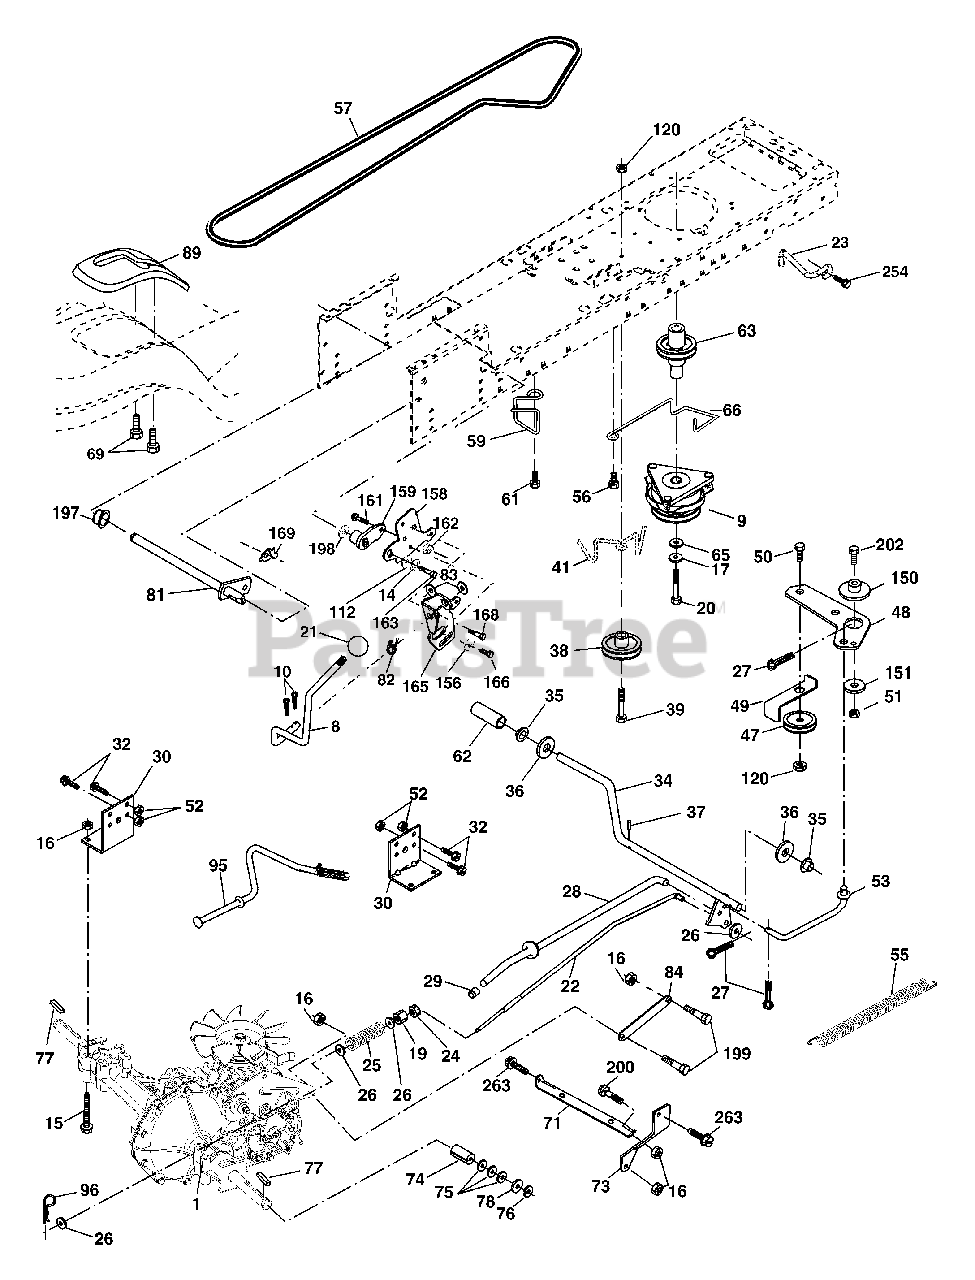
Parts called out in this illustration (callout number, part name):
8	Rod Shift Fender Adjust STLT
9	Clutch Elecric
10	Pin Cotter 1/8 x 1 CAD
14	Washer Lock Hvy Helical
15	Bolt Hex 5/16-18 unc Flghd
16	Nut Lock Hex W/Ins. 5/16-18 unc P
19	Nut Lock Hex W/Ins 3/8-16 unc
20	Bolt, Hex 7/16-20 x 4-1/4 Ga. 5
21	Knob Deluxe 1/2-13 unc BLK/BLK
22	Rod, Brake Hydro
23	Bracket Asm Mtg CL
24	Nut Hex Jam 3/8-16 unc
25	Spring, Brake Rod
26	Washer
27	Pin Cotter 1/8 x 3/4 CAD.
28	Rod, Parking Brake
29	Cap,Parking Brake
30	Bracket, Transaxle
32	Bolt Hex Hd 5/16-18 unc x 3/4
34	Shaft, Foot Pedal
35	Bearing, Nylon
37	Pin, Roll
38	Pulley, Composite
39	Bolt Rdhd 3/8-16 unc x 2-3/4 Gr. 5
41	Keeper, Belt Idler
47	Pulley, Idler, V-Groove Plastic
48	Bellcrank Clutch Grnd Drv STL
49	Retainer, Belt Style Spring
50	Bolt 3/8-16 x 1-1/2 Gr. 5
52	Nut Crownlock 5/16-18
53	Link, Clutch
55	Spring, Return, Clutch
56	Screw 3/8-16 x 1-1/4
57	V-Belt, Ground Drive
59	Keeper, Center Span
61	Screw 3/8-16 x .875
62	Cover, Pedal
63	Pulley, Engine
65	Washer Lock Hvy HLCL Spr 7/16
66	Keeper Belt Engine
69	Screw Hex Wsh Hi-Lo 1/4-1/2 unc
71	Strap Torque Lh Hydro
73	Strap Torque Rh Hydro
74	Spacer, Axle
75	Washer 25/32 x 1-1/4 x 16 Ga.
77	Key, Square
78	Washer 25/32 x 1-5/8 x 16 Ga.
81	Shaft Asm Cross Tapered
82	Spring Torsion T/A
83	Washer 17/32 x 3/4 x 16 Ga.
84	Link Transaxle
89	Console, Shift
95	Control Asm. Bypass Hydro
96	Retainer Spring 1" Zinc/Cad
112	Washer 9/32 x 3/4 x 10 Ga.
116	Bolt Rdhd Sqnk 3/8-16 unc x 1
120	Nut Lock Flg 3/8-16
150	Spacer Retainer
151	Washer 13/32 x 2 x 10 Ga.
156	Washer Srrted 5/16 ID x 1.125
158	Bracket Shift Mount
159	Hub Shift
161	Bolt Rdhd Sqnk 1/4-20 x 3/4 Gr. 5
162	Nut Crownlock 1/4-20 unc
163	Bolt Hex Fin 1/4-20 unc x 1 Gr. 5
165	Bracket Pivot Lever
166	Screw 5/16-18 x 5/8
168	Bolt Shoulder 5/16-18 x .561
169	Plate Fastening STLT/CRD
197	Nyliner Snap 5/8" ID
198	Washer Nyl 7/8 ID x .105 Hyd
199	Bolt Shoulder 5/16-18 unc
200	Bolt Rdhd Sqnk 5/16-18 unc x 1
202	Bolt 3/8-16 x 1-3/4 Gr. 5
212	Nut Hex Flange Lock
263	Screw Hex wsh Thdr 3/8-16 x 3/4
